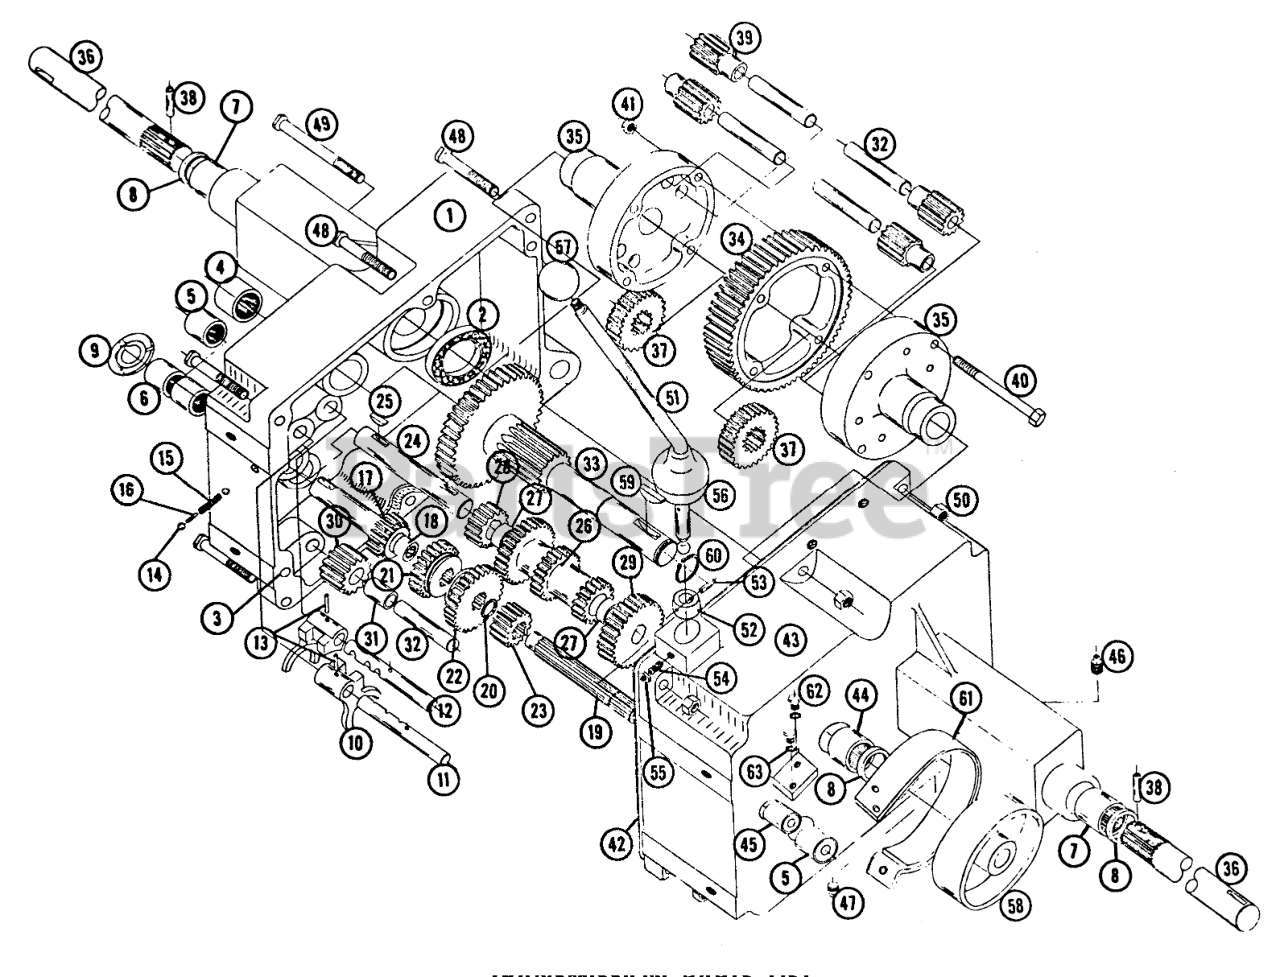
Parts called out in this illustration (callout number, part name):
3	PIN-DOWEL
4	BEARING-NEEDLE
5	BEARING-NEEDLE
7	BEARING-NEEDLE
10	FORK-SHIFT
13	PIN-ROLL
14	BALL-DETENT
18	BEARING-NEEDLE
20	Snap Ring 3/4 I.D.
23	GEAR
25	Key
27	BUSHING-BRONZE
29	GEAR-CLUSTER SHAFT
30	GEAR/BUSHING ASM-REVERSE IDLER
31	BUSHING
32	PIN-DIFFERENTIAL
34	SVC BULLT 394
35	DIFFERENTIAL CASE
37	AXLE GEAR
42	GASKET-TRANSMISSION
46	Plug 1/4 Pipe
47	Plug 3/8 Pipe
48	Bolt, 3/8 16 x 2
49	Bolt Hex 3/8-16 x 1
51	Stick-Shift
53	Roll Pin
54	Screw Soc. Hd.-Set 1/4-20 x 3/4
55	Nut 1/4-20
56	COVER-DUST
59	KEY-WOODRUFF
60	Snap Ring 1" Shaft
62	Bolt-1/4-20 x 5/8
